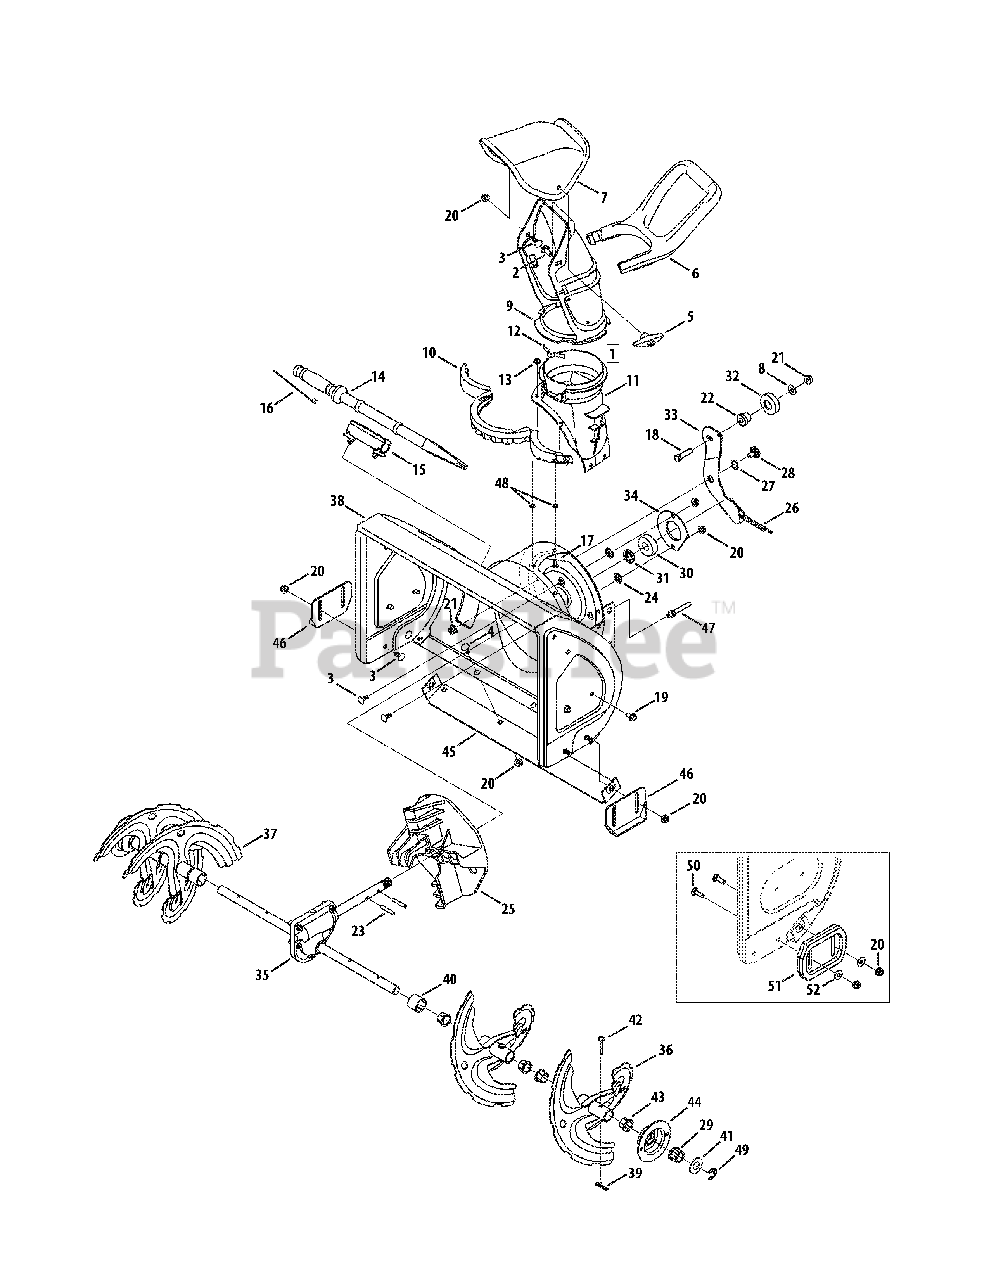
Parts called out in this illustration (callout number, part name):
1	Chute Assembly
2	Carriage Bolt 5/16-18 x 1.0"
3	Carriage Bolt 5/16-18
4	Carriage Bolt 5/16-18 x .62
5	Wing Knob 5/16-18
6	Chute Handle
7	Upper Chute
8	Flat Washer .385 x .87 x .06
9	Lower Chute
10	Chute Ring
11	Chute Adapter 5" Dia.
12	Chute Adjustment Spring
13	Flange Lock Nut 1/4-20
14	Clean-out Tool
15	Clean-out Tool Mount
16	Cable Tie
17	Carriage Screw 1/4-20 x 0.62"
18	Hex Bolt 3/8-16 x 1.50"
19	AB Screw 5/16-18 x .750
20	Flange Lock Nut, 5/16-18
21	Flange Lock Nut, 3/8-16
22	Shoulder Spacer
23	Spiral Pin
24	Push On Nut
25	Impeller
26	Extension Spring
27	Wave Washer
28	Shoulder Screw 3/8-16
29	Hex Flange Bearing
30	Ball Bearing
31	Spacer
32	Flat Idler
33	Auger Idler Bracket
34	Bearing Housing
35	Auger Gearbox Assembly
36	Auger Assembly - LH
37	Auger Assembly - RH
38	Auger Housing, 22"
39	Bow Tie Cotter Pin 72
40	Spacer, 1.25 x.75 x 1.00
41	Flat Washer, .76 x 1.49 x .06
42	Shear Pin,.25 x 1.50
43	Flange Bushing
44	Hex Bearing Housing
45	Shave Plate 2.25 x 21.66 LG
46	Skid Shoe
47	Belt Keeper
48	Push Nut
49	E-Ring, .750
50	Screw, Carriage, 5/16-18 x 1.00
51	Slide Shoe
52	Washer, Flat, .349 x .879 x .063
